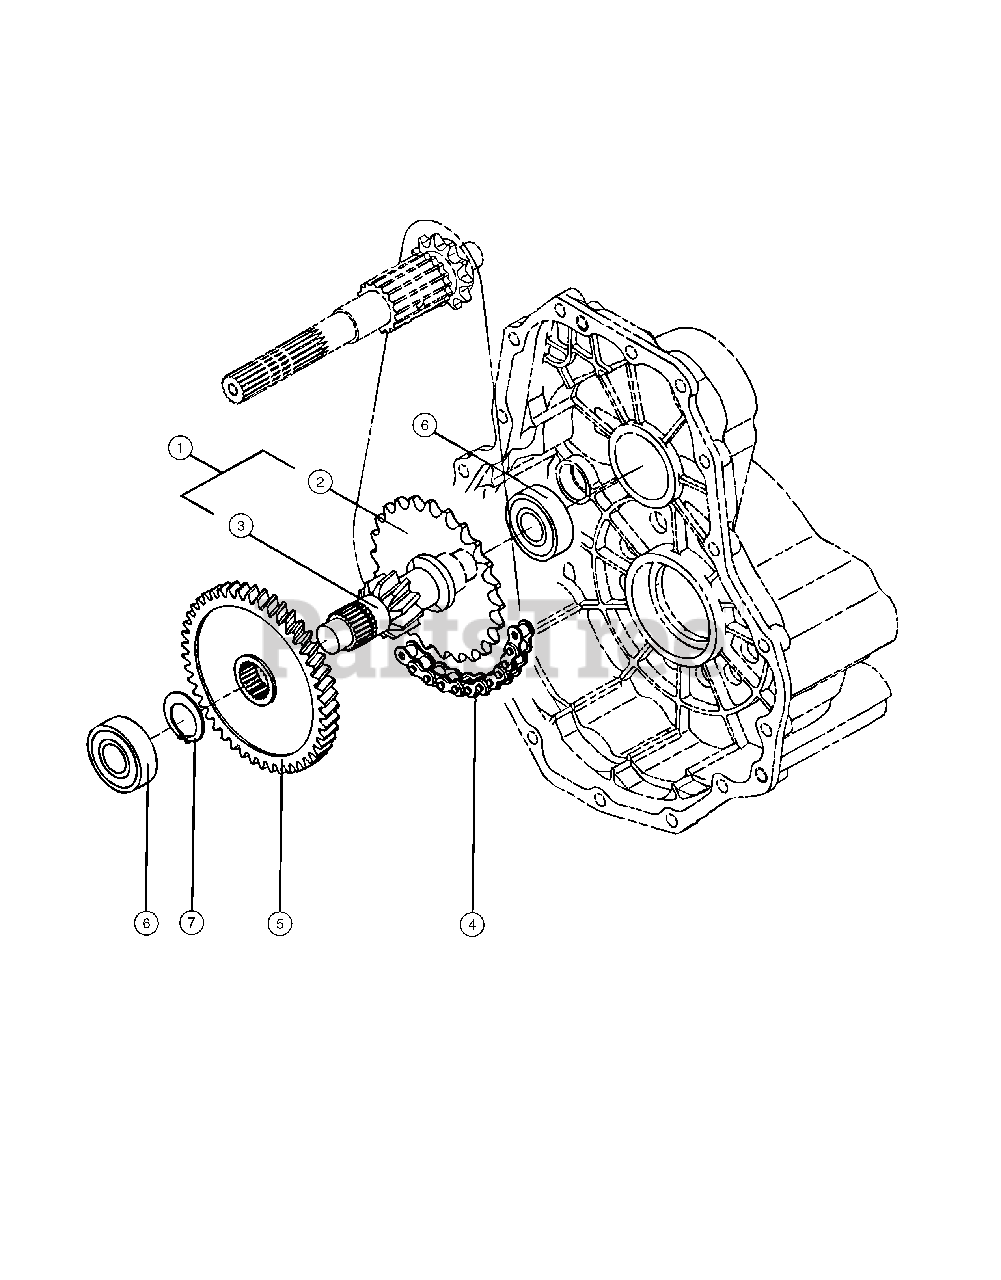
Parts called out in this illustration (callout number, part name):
1	Reduction Shaft Assembly
2	Sprocket, 27
3	Shaft, Reduction
4	Chain, 40 x 34
5	Gear, 46H, Reduction
6	Bearing, 6204R, SH2
7	Ring, 26
